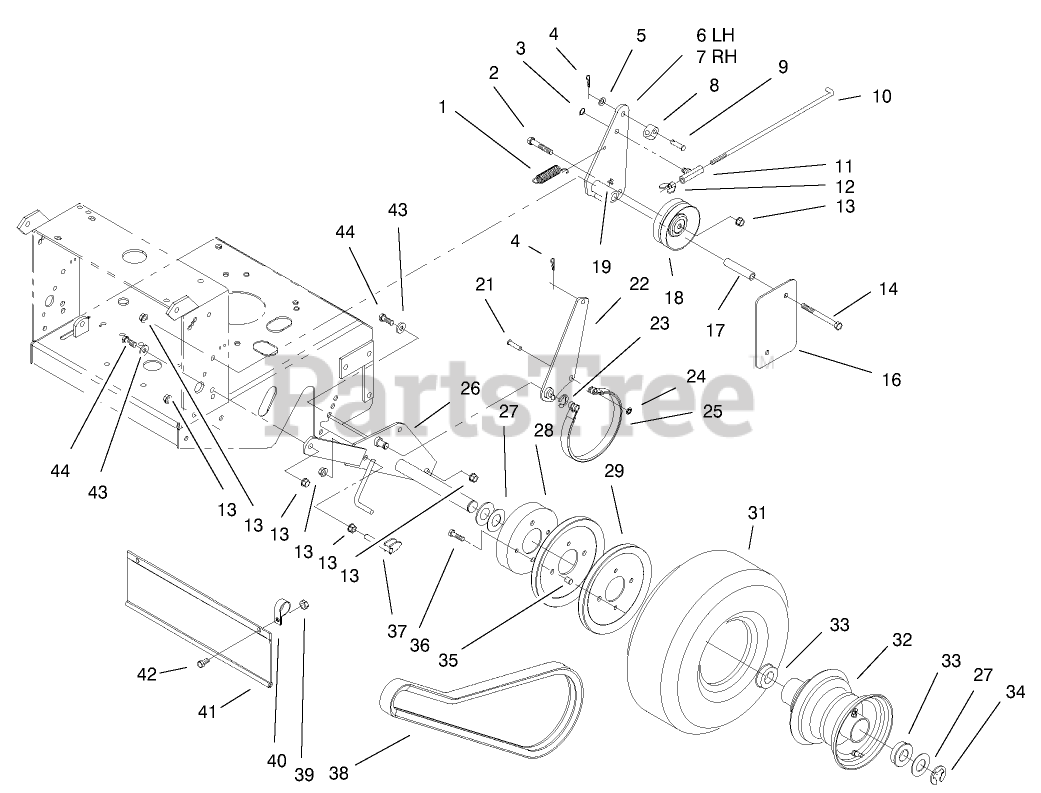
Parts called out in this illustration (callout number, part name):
1	SPRING-EXTENSION
2	SCREW-HH
3	RING-RETAINING
4	PIN-COTTER
5	WASHER-PLAIN
6	RH IDLER ARM ASM
7	LH IDLER ARM ASM
8	FITTING-ROD
9	PIN-CLEVIS
10	ROD-BRAKE
11	SWIVEL-BRAKE
12	WINGNUT-NYLOCK
13	NUT-HHF, WHIZ
14	SCREW-HH
16	SHIELD-WHEEL, DRIVE
17	SPACER-SHIELD
18	IDLER-DRIVE, WHEEL
19	FITTING-GREASE
21	PIN-CLEVIS
22	ARM-BRAKE
23	RING-RETAINING, EXTERNAL
24	NUT-PUSH
25	BAND-BRAKE
27	WASHER-SPACER
28	DRUM-BRAKE
29	SHEAVE-WHEEL, DRIVE
31	Tire-Turfmaster
32	WHEEL AND HUB ASM
33	BEARING-FLANGED
34	RING-SNAP
35	SPACER-SHEAVE, WHEEL
36	SCREW-HH
37	SCRAPER
38	V-BELT
39	NUT-LOCK, NI
40	CLAMP-R
41	SHIELD-TRAILING
42	SCREW-HH
43	WASHER-BELLEVILLE
44	SCREW-HH
